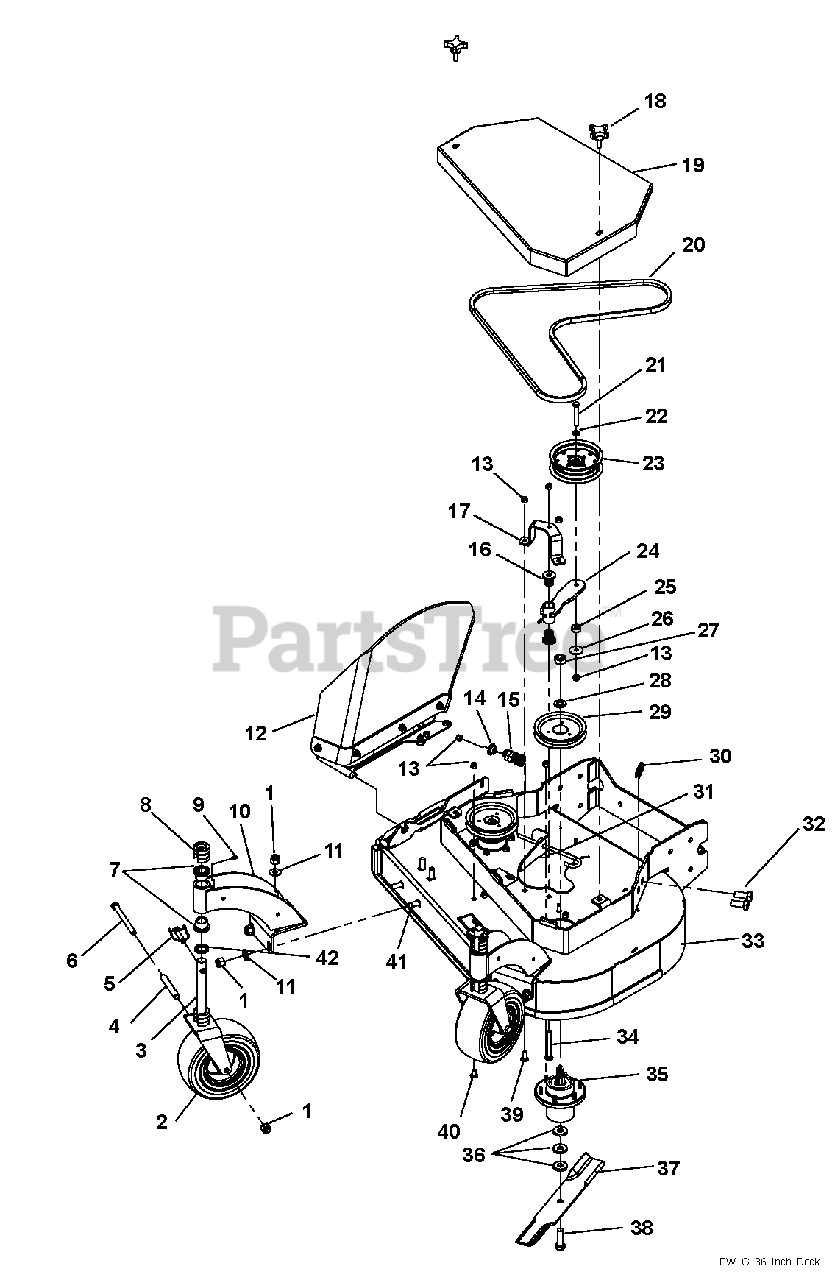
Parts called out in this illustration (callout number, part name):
1	LOCKNUT, 1/2-13 NYLOC Y
2	ASSY, WHEEL AND TIRE 9X3.5
3	WLDT, CASTER YOKE GD BLACK
4	TUBE, CASTER AXLE
5	PIN, KLIK .438X2.00
6	BLT-HEX .50-13X5.50 GR5YWZC
7	BRG, FLG 1.00X1.25X1.00
8	C-SPACER, 1.00 X 1.77 X .500
9	FTG, 1/4-28 STRGT GREASE ZERK
10	WLDT, STRUT FRONT FXWLK SCAMPR
11	MANUAL, OWNERS RAPID XZ FRENCH
12	ASSY, DISCHARGE SHIELD GD
13	LOCKNUT, 3/8-16 NYLOC Y
14	KEEPER, SPRING
15	SPRING, COM 1.22X.162X2.50 Y
16	BRG, FLG M10XM25XM27 FLUTED
17	BRACE, TENSIONER ARM
18	KNOB, 3/8 X 1.25 - 4 PRONG
19	WLDT, BELT SHIELD 36 FXWLK GD
20	BELT, HB 77.5 EL AMD OHR
21	BLT-HEX .38-16X2.75 GR5 YWZC
22	WASHER, .406X.813X.065 FLAT Y
23	PULLEY, FLAT 5.00X.375 W/BRG
24	WLDT, IDLER 36 FXWLK G2
25	BUSHING, .380 X 1.00 X .410 Y
26	WASHER, .375X1.50X.063 FLAT Y
27	LOCKNUT, 3/4-16 CROWN PL
28	WASHER, .75X1.3125X.120
29	PULLEY, SPLINE SPINDLE LSE
30	TRIM, LOCK 1/4" EDGE
31	J-BOLT, 3/8-16 X 7.88 Y
32	BOLT, HEX 5/8-11 1.5" GR8 YWZC
33	ASSY, DECK 36" SCAMPER W/DECAL
34	BOLT, 3/8-16X3.50 CRG 5 Y
35	ASSY, SPINDLE S/O
36	WASHER, .630X1.50X.250 FLAT Y
37	BLADE, 18.000 X .80 LIFT
38	BOLT, 5/8-11 X 2.00 HEX 8 Y
39	BOLT, 3/8-16X1.00 CRG 5 SN Y
40	BLT-RDHDSQNK .38-16X.75 G5YZ
41	BLT-RDHDSQNK .50-13X1.50 G5YZ
42	BUSHING, 1.03 X 1.50 X .179 Y
